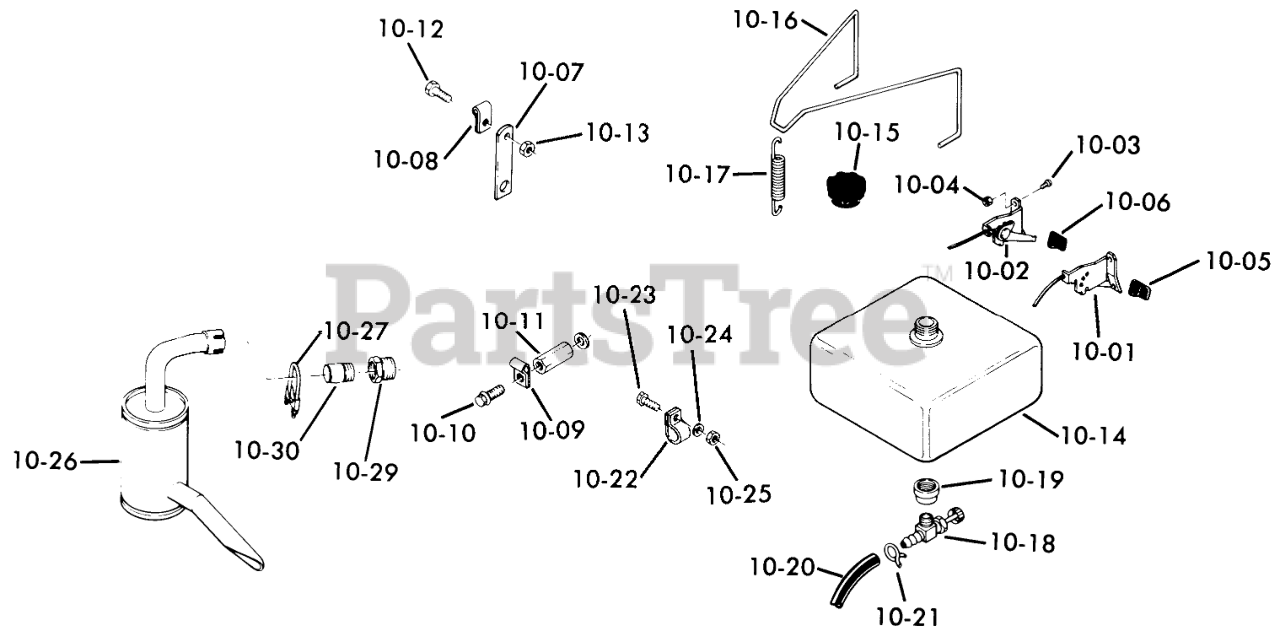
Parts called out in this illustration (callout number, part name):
10-01	Choke Control
10-02	THROTTLE CONTROL
10-03	SCREW
10-04	#10-24 Kep-Nut
10-05	KNOB-CHOKE
10-06	KNOB-THROTTLE
10-07	Strap
10-08	THROTTLE CONTROL CLP
10-09	Clip
10-10	Screw
10-11	Special Nut
10-12	Screw
10-13	Nut
10-14	ASSY-FUEL TANK
10-15	Cap
10-16	HOLD DOWN WIRE
10-17	CLUTCH SPRING
10-18	VALVE-FUEL
10-19	BUSHING
10-20	Fuel Hose
10-21	Clamp
10-22	CLAMP-HOSE
10-23	Bolt
10-24	WASHER 5/16 SAE
10-25	Nut
10-26	Muffler
10-27	ASSY-MUFFLER CLAMP
10-29	REDUCER 1 1/4-1
